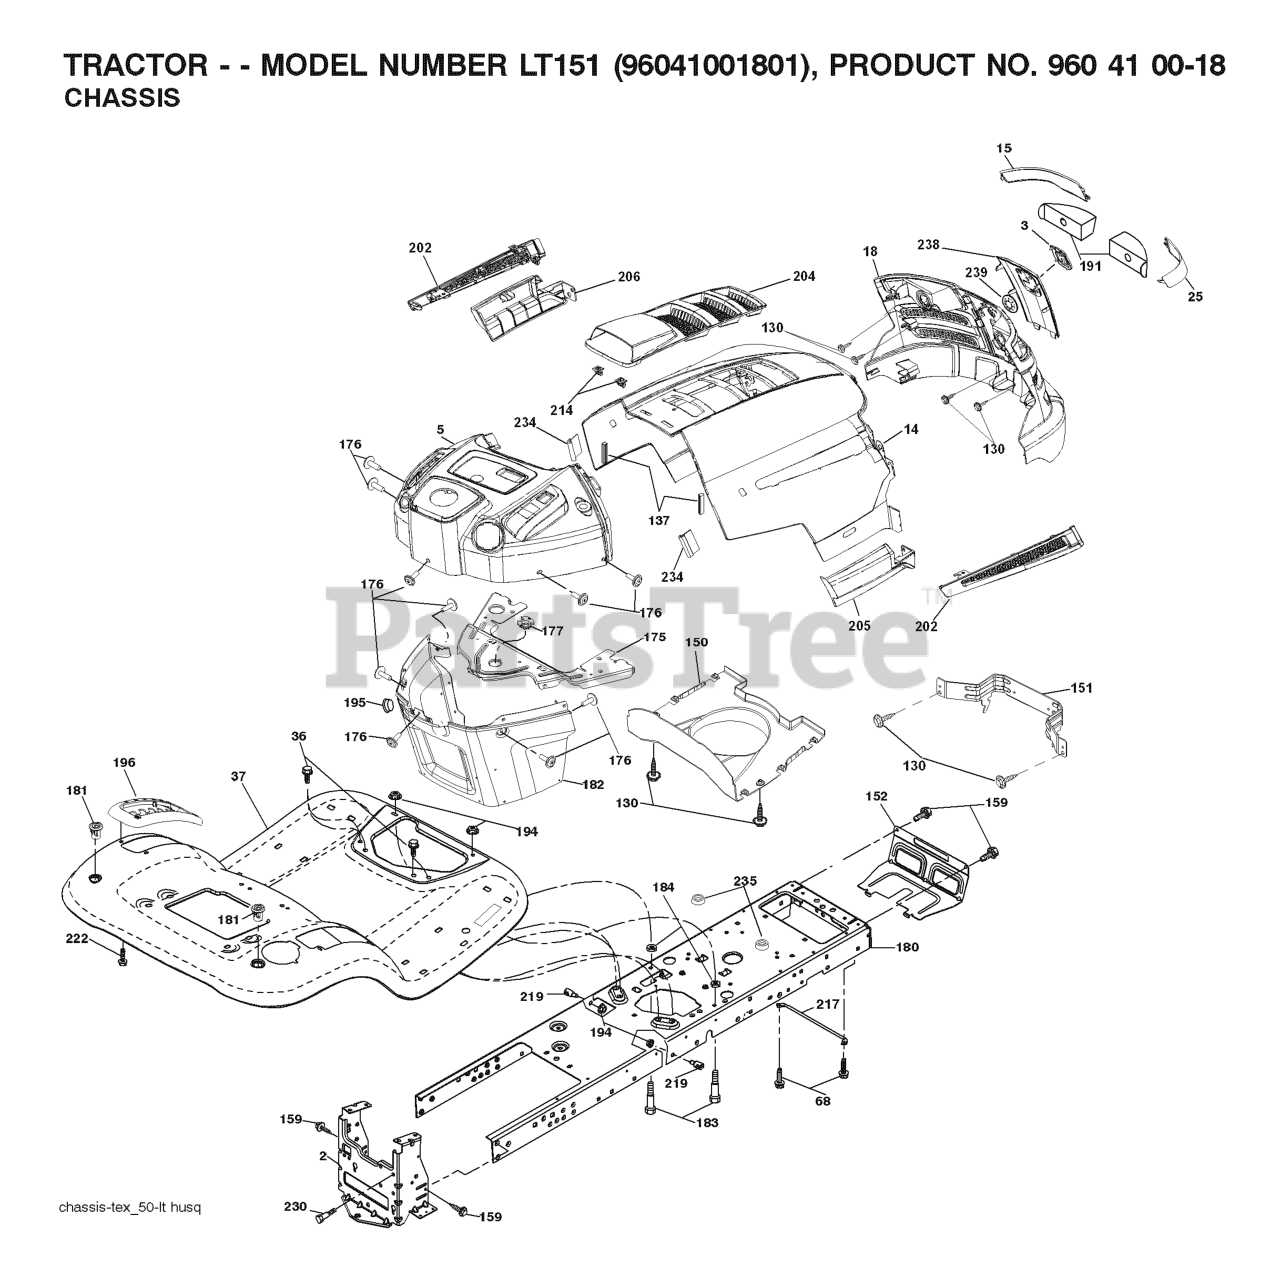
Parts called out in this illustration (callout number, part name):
2	DRAWBAR.1PC.NSTL
3	RP LOGO
5	DASH
14	HOOD
15	LENS.HUSQVARNA LT.LH
18	RP GRILLE/LENS ASM.
25	LENS.HUSQVARNA LT.RH
36	SCREW 3/8-16X3/4
52	LOCKNUT
68	Screw 5/16-18 x 1/2 Hex, Self Tapping 5/16-18 x 1/2
130	SCREW
137	BUMPER DASH
151	BRACKET PIVOT
152	SHIELD.BROWNING/DEBRIS
159	SCREW, 3/8-16X3/4
175	CROSSMEMBER
176	SCREW.#10-24X5/8.RN.QU
177	BUSHING STEERING
180	CHASSIS.STAMPING.LT/GT
181	BUSHING.MNT.FEND.CRGO.
182	DASH LOWER
183	BOLT.5/16-18X1-1/4 FULL.THREAD
189	SCREW
191	INSERT REFLECTIVE
194	NUT LOCK HEX FLANGE 5/16-18
195	PLUG DASH
196	CONSOLE.ASM.DECK.LIFT.
202	VENT SIDE HOOD RH
203	VENT SIDE HOOD LH
204	VENT TOP HOOD
205	SKIRT SIDE RH
206	SKIRT SIDE LH
214	CLIP.RETAINER.TINNER.
217	ROD PIVOT CHASSIS/HOOD
219	STUD.FASTNER.W/ANTI-ROTATE
222	SCREW.1/4-20X5/8
230	SHOULDER BOLT 5/16-18TT
234	BUMPER.HOOD.TEX.HUSQVARNA
235	SPACER FENDER
236	NUT.CENTERLOCK.5/16-
238	TRIM
239	NUT PUSH M
